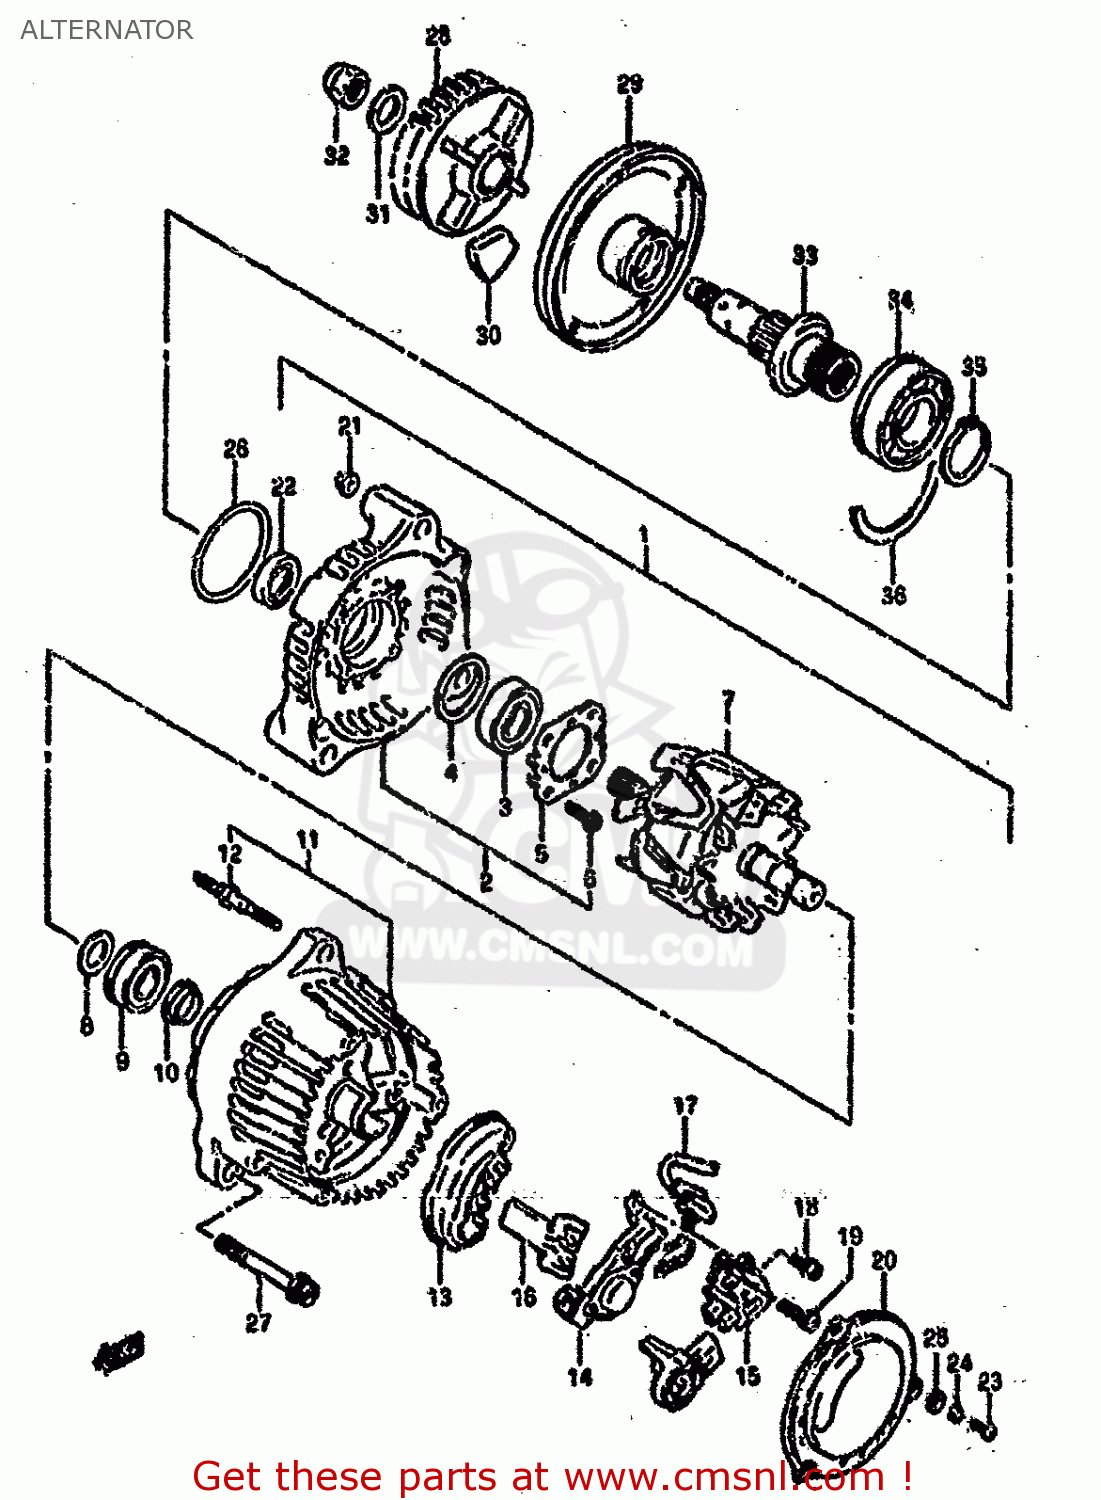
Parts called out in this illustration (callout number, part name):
1	ALTERNATOR ASSEMBLY
2	FRAME,DRIVE END
3	BEARING
4	COVER,BEARING
5	RETAINER,BEARING
6	SCREW,BEARING RETAINER
7	ROTOR ASSEMBLY
8	COVER,BEARING
9	BEARING
10	COVER(2)
11	FRAME,END
12	STUD BOLT
13	HOLDER,RECTIFIER
14	REGULATOR
15	HOLDER,BRUSH
16	COVER,RECTIFIER
17	WIRE,LEAD
18	SCREW 4X6
19	SCREW
20	COVER
21	NUT
22	SERVICE KIT(A)
23	SCREW
24	WASHER,LOCK
25	WASHER,5MM
26	O RING
27	BOLT
28	GEAR,GENERATOR DRIVEN
29	HOUSING,GENERATOR DAMPER
30	DAMPER,GENERATOR
31	WASHER
32	NUT
33	SHAFT,GENERATOR DRIVE
34	BEARING(25X52X15)
35	CIRCLIP
36	C RING
